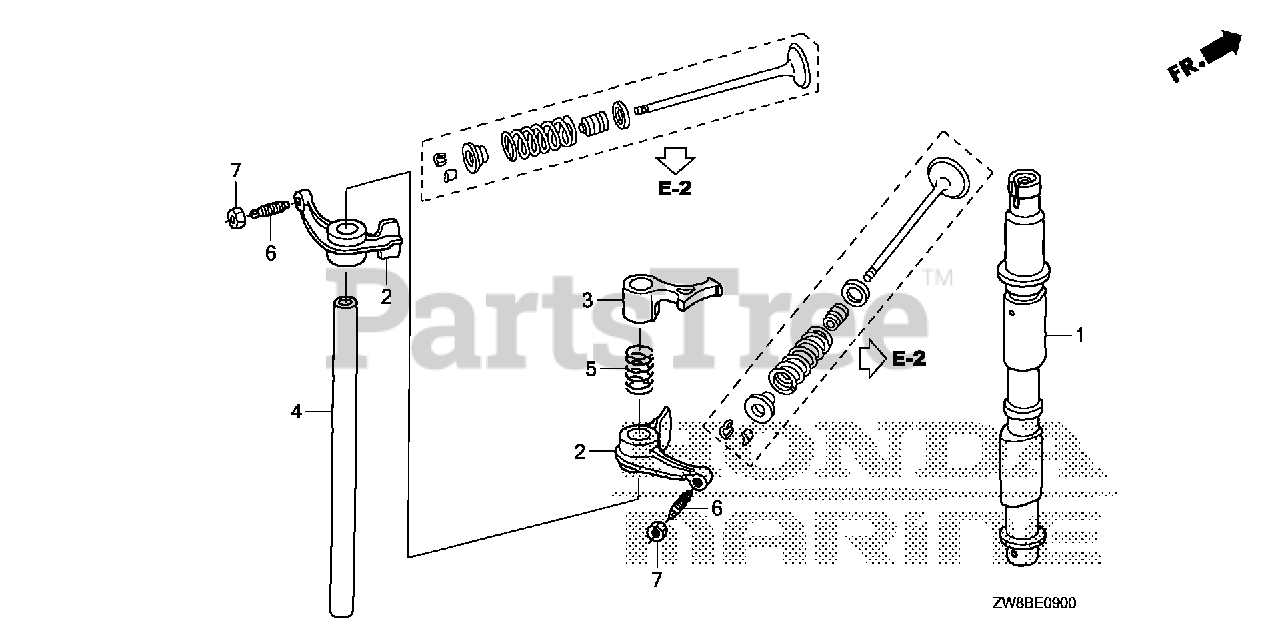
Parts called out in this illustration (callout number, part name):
2	ARM, VALVE ROCKER
3	ARM, FUEL PUMP ROCKER
4	SHAFT, ROCKER ARM
5	SPRING, ROCKER ARM
6	SCREW, TAPPET ADJUSTING
7	NUT, TAPPET ADJUSTING
